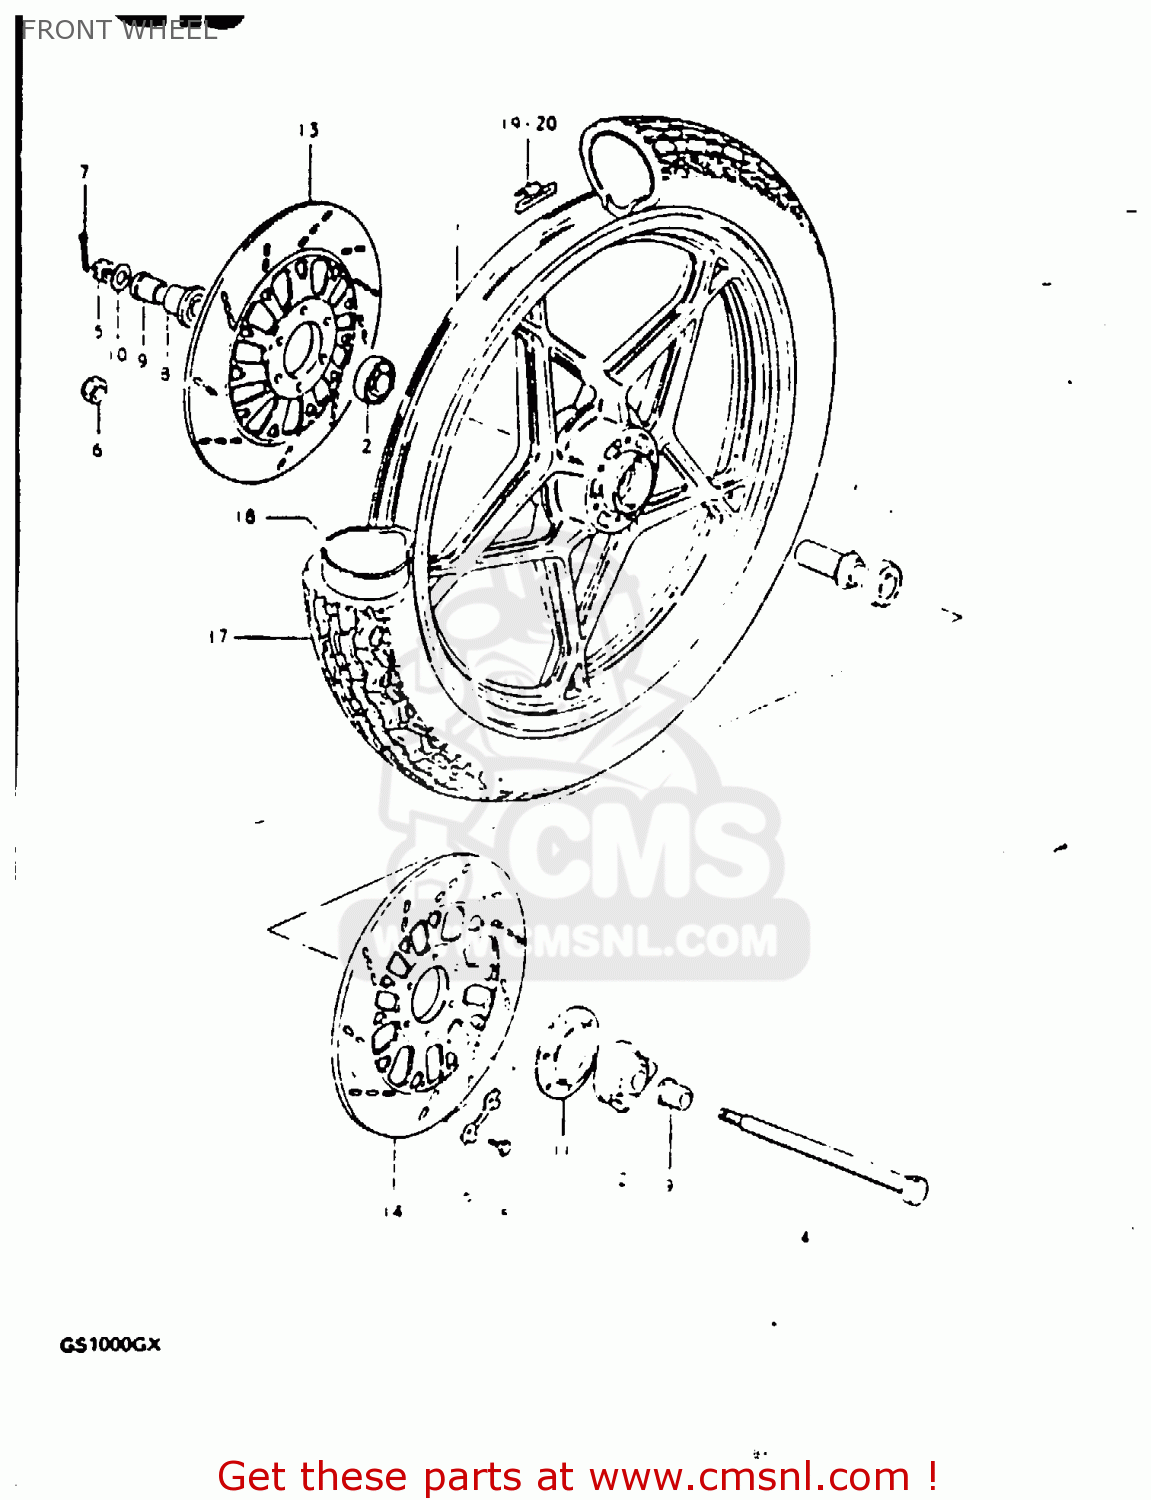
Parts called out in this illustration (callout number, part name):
1	CASTING WHEEL,FRONT 1.85
2	BEARING
3	SPACER,FR HUB BEARING
4	AXLE,FR
5	NUT 12MM
7	COTTER PIN
8	SPACER,FR AXLE,R
9	SPACER,FR AXLE,L
10	WASHER
11	DUST SEAL,SPEEDOMETER GEAR BOX
12	BOX ASSEMBLY,SPEEDOMETER GEAR
13	DISC,FR BRAKE,R
14	DISC,FR BRAKE,L
15	BOLT(8X25)
16	WASHER
17	TIRE,FRONT
18	TUBE,INNER
19	BALANCER,WHEEL
20	BALANCER,WHEEL
